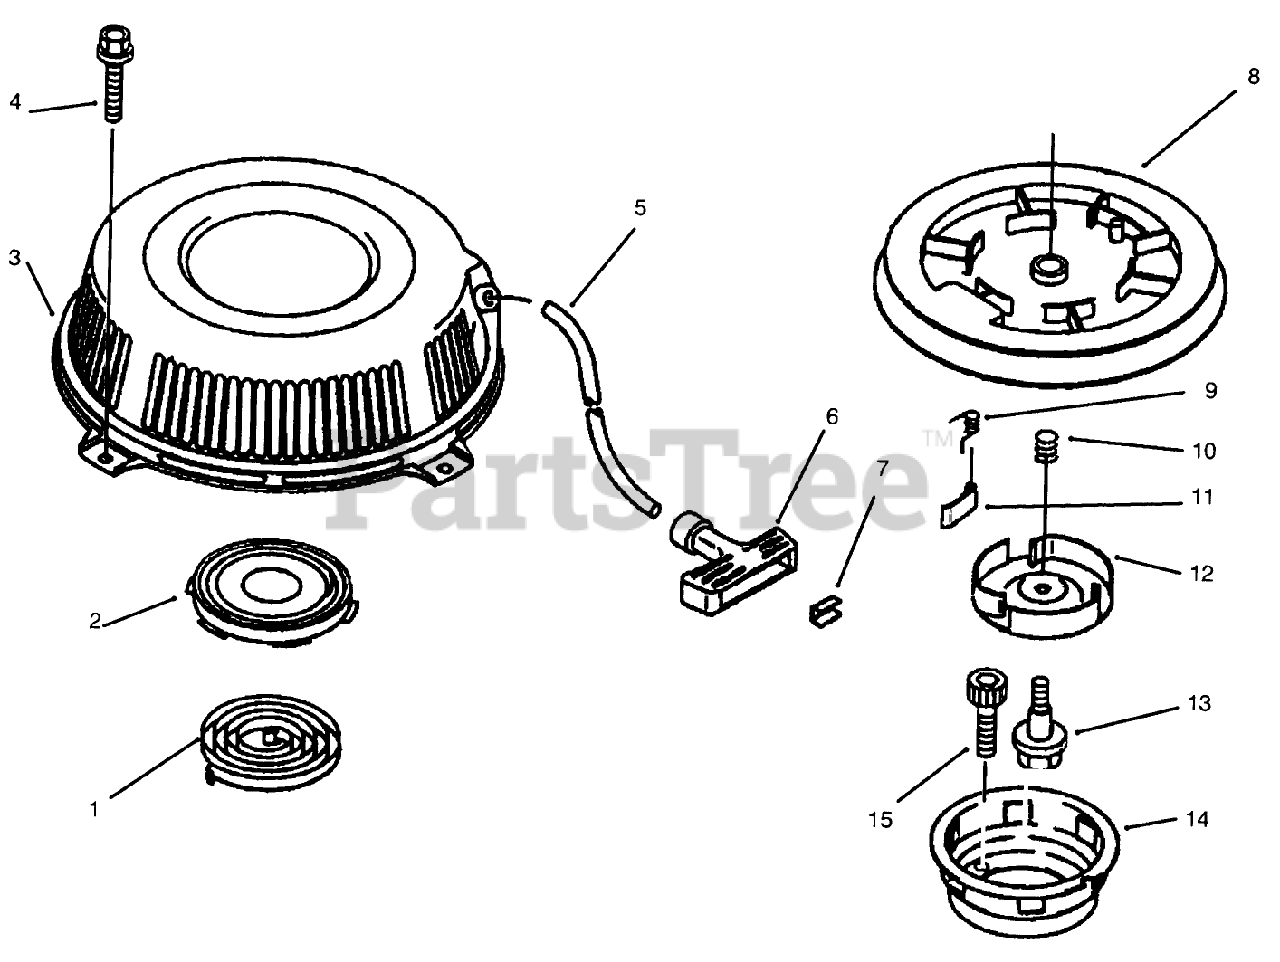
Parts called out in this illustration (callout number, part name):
1	Spring-Recoil
2	Case
3	Case-Recoil Starter
4	BOLT-FLANGED (6X10)
5	Rope
6	Grip
7	Washer
8	Reel
9	Spring
10	Spring
11	Pawl
12	Retainer
13	Bolt
14	Pulley-Starting
15	Bolt-Socket
